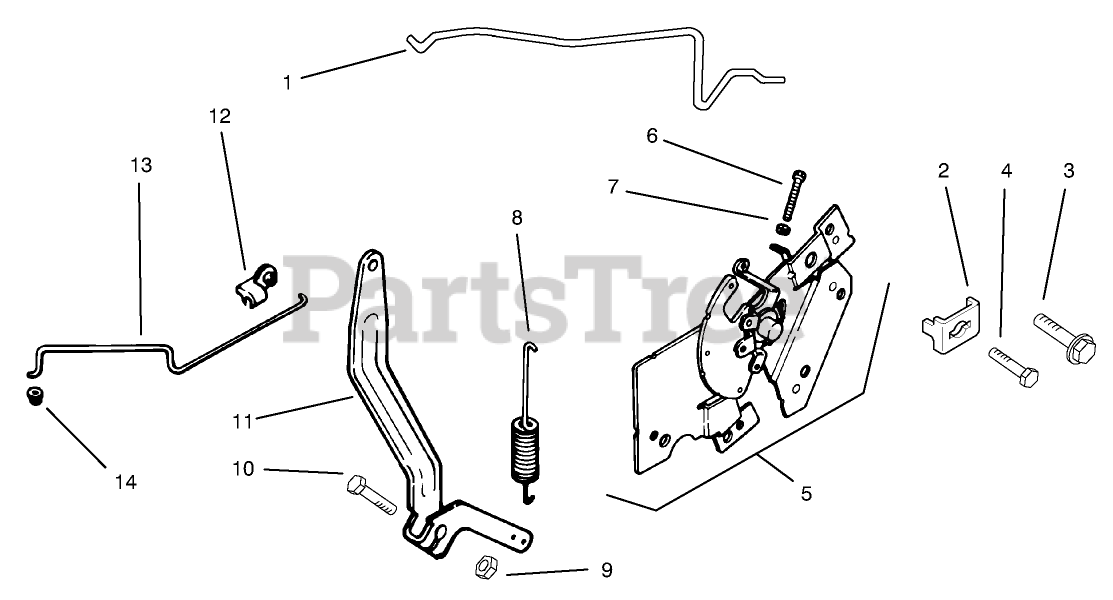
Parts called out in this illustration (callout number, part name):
1	Linkage-Choke (Only On: 72042,72043,72062,72063)
3	Screw Socket
4	Screw M5x0.8x16 (Only On: 72042, 72063, 72062, 72043)
5	Control-ASM INC 6-7 (Only On: 72042, 72063, 72062, 72043)
6	Screw-HHF M4x0.7x28 (Only On: 72042, 72063, 72062, 72043)
7	Nut
8	Spring-Governor (Only On: 72042, 72063, 72062, 72043)
11	Lever-Governor (Only On: 72042, 72063, 72062, 72043)
12	Bushing-Linkage
13	Linkage-Throttle (Only On: 72042, 72063, 72062, 72043)
14	Bushing
